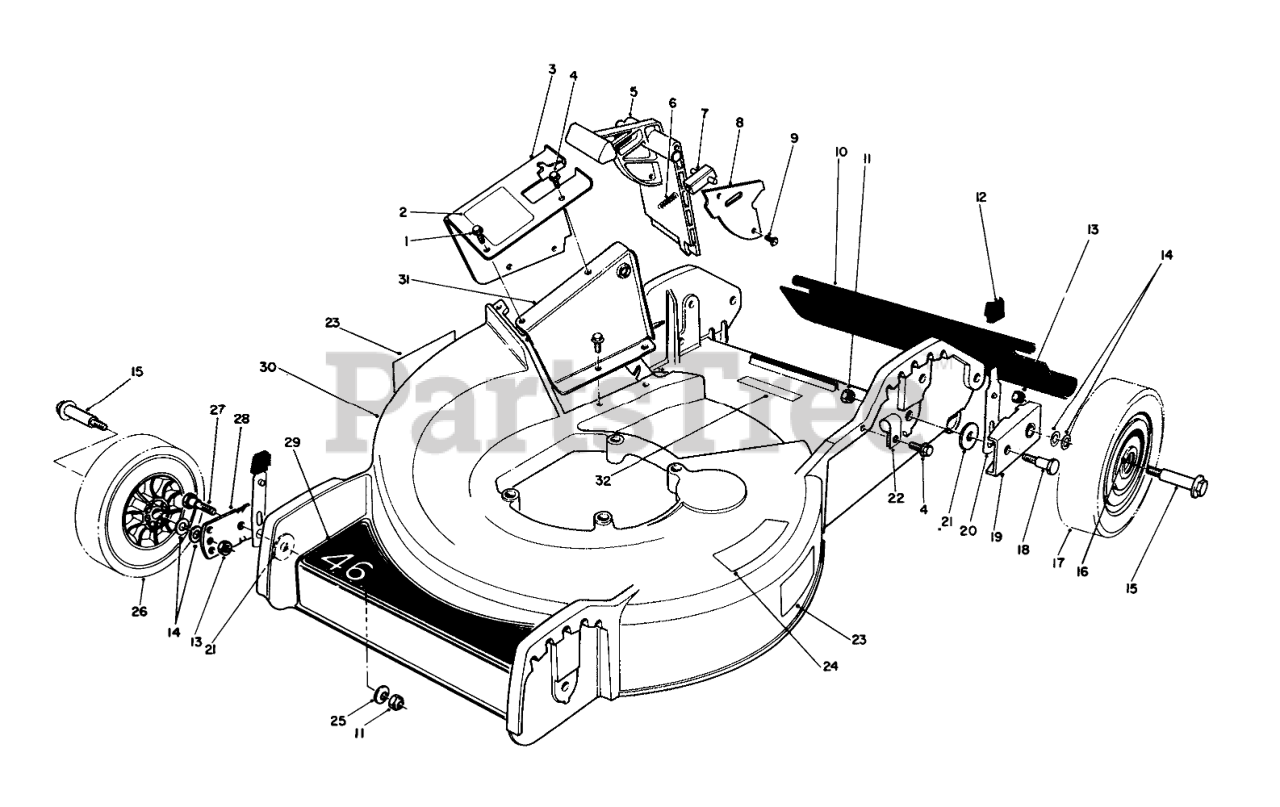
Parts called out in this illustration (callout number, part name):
1	SCREW
2	DECAL - DANGER
3	Tunnel-Outer (Incl. Ref. #2)
4	SCREW
5	Door Mulching
6	SPRING-COMPRESSION, LATCH
7	Door Latch
8	Cover Door
10	SHIELD - TRAILING
11	NUT-LOCK, NI
12	KNOB-ARM
13	Nut
14	WASHER
15	BOLT-WHEEL
16	BUSHING
17	Wheel & Tire Assembly (Incl. Ref. #16)
18	PIVOT SCREW
19	PIVOT ARM ASM
20	SPRING ARM ASM
21	PIVOT WASHER
22	CLAMP-CABLE
23	Decal Danger
24	DECAL - STEP PAD INT'L
25	WASHER-BELLEVILLE
26	Wheel & Tire Assembly (Inc. Ref. #16)
27	5/16-18 PIVOT SCREW
28	PIVOT ARM ASSY
29	DECAL - DECK
30	Housing (Incl. Ref . #23)
31	Tunnel-Inner
32	Decal
